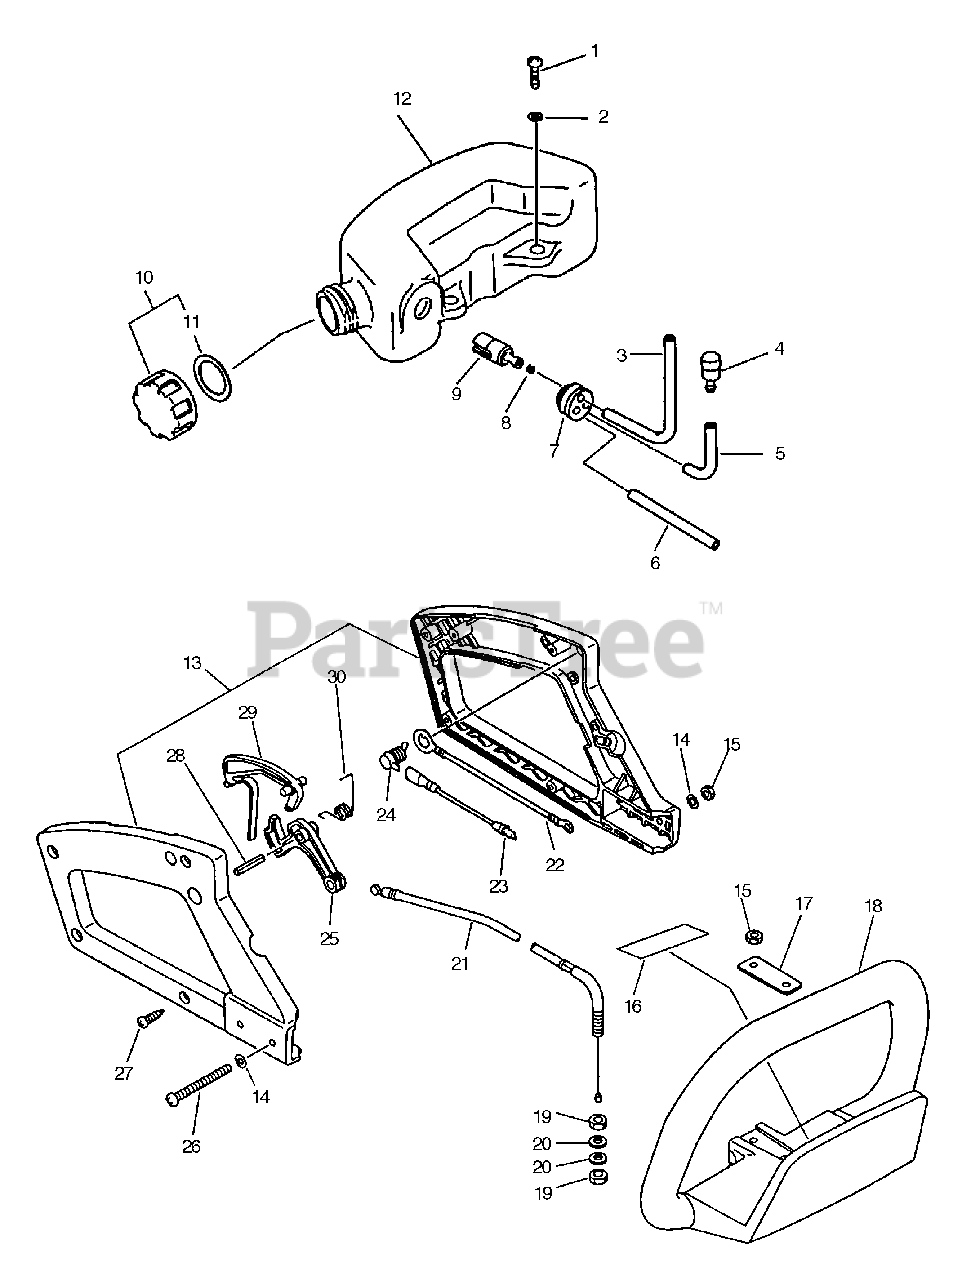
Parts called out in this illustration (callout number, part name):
1	SCREW 5×16
2	WASHER 5.5×12×0.8
3	PIPE, FUEL
4	VENT ASSY
5	PIPE, FUEL 3x-5x-70 BLACK
6	PIPE, FUEL RETURN 3×6×110
7	GROMMET, FUEL
8	CLIP 6 MM
9	FILTER, FUEL
10	CAP ASSY, FUEL
11	GASKET, FUEL CAP
12	TANK, FUEL
13	HANDLE SET, REAR
14	WASHER, FLAT 5.5×10×0.8
15	NUT, LOCK M5
16	LABEL, CAUTION
16	LABEL - CAUTION
17	PLATE, EYE
18	HANDLE, SUPPORT
20	WASHER 6.5×11.5×0.8
21	CABLE, THROTTLE
22	LEAD - GROUND
23	LEAD - GROUND
24	SWITCH, ON-OFF
25	TRIGGER, THROTTLE
26	SCREW 5×47
27	SCREW 4×16
28	PIN, SPRING Ø5×25 MM
29	LOCKOUT, THROTTLE
30	SPRING, THROTTLE RETURN
